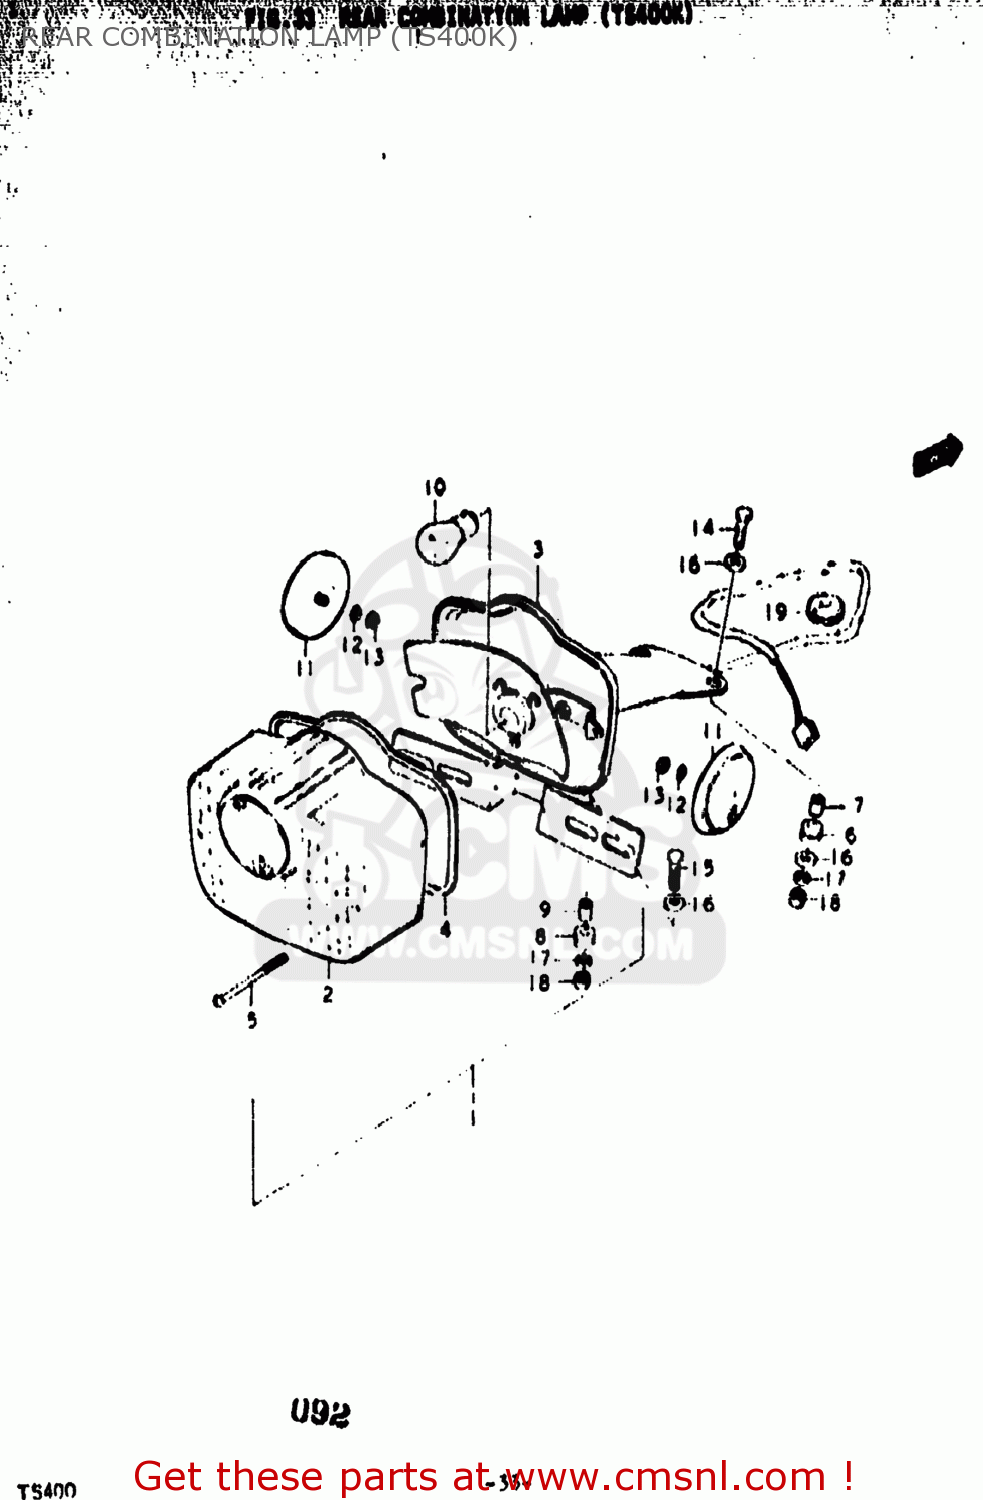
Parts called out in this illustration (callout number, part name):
1	LAMP ASSEMBLY,REAR COMBINATION
2	LENS,REAR COMBINATION LAMP
3	HOUSING,REAR COMBINATION LAMP
4	GASKET (NAS)
5	SCREW
6	CUSHION
7	SPACER,REAR COMBINATION LAMP
8	CUSHION
9	SPACER,REAR COMBINATION LAMP
10	BULB(12V23W)
11	REFLECTOR,REFLEX
12	LOCK WASHER
13	NUT
14	BOLT
15	BOLT
16	WASHER (6.5X20X1.2)
17	LOCK WASHER
18	NUT
19	GROMMET
